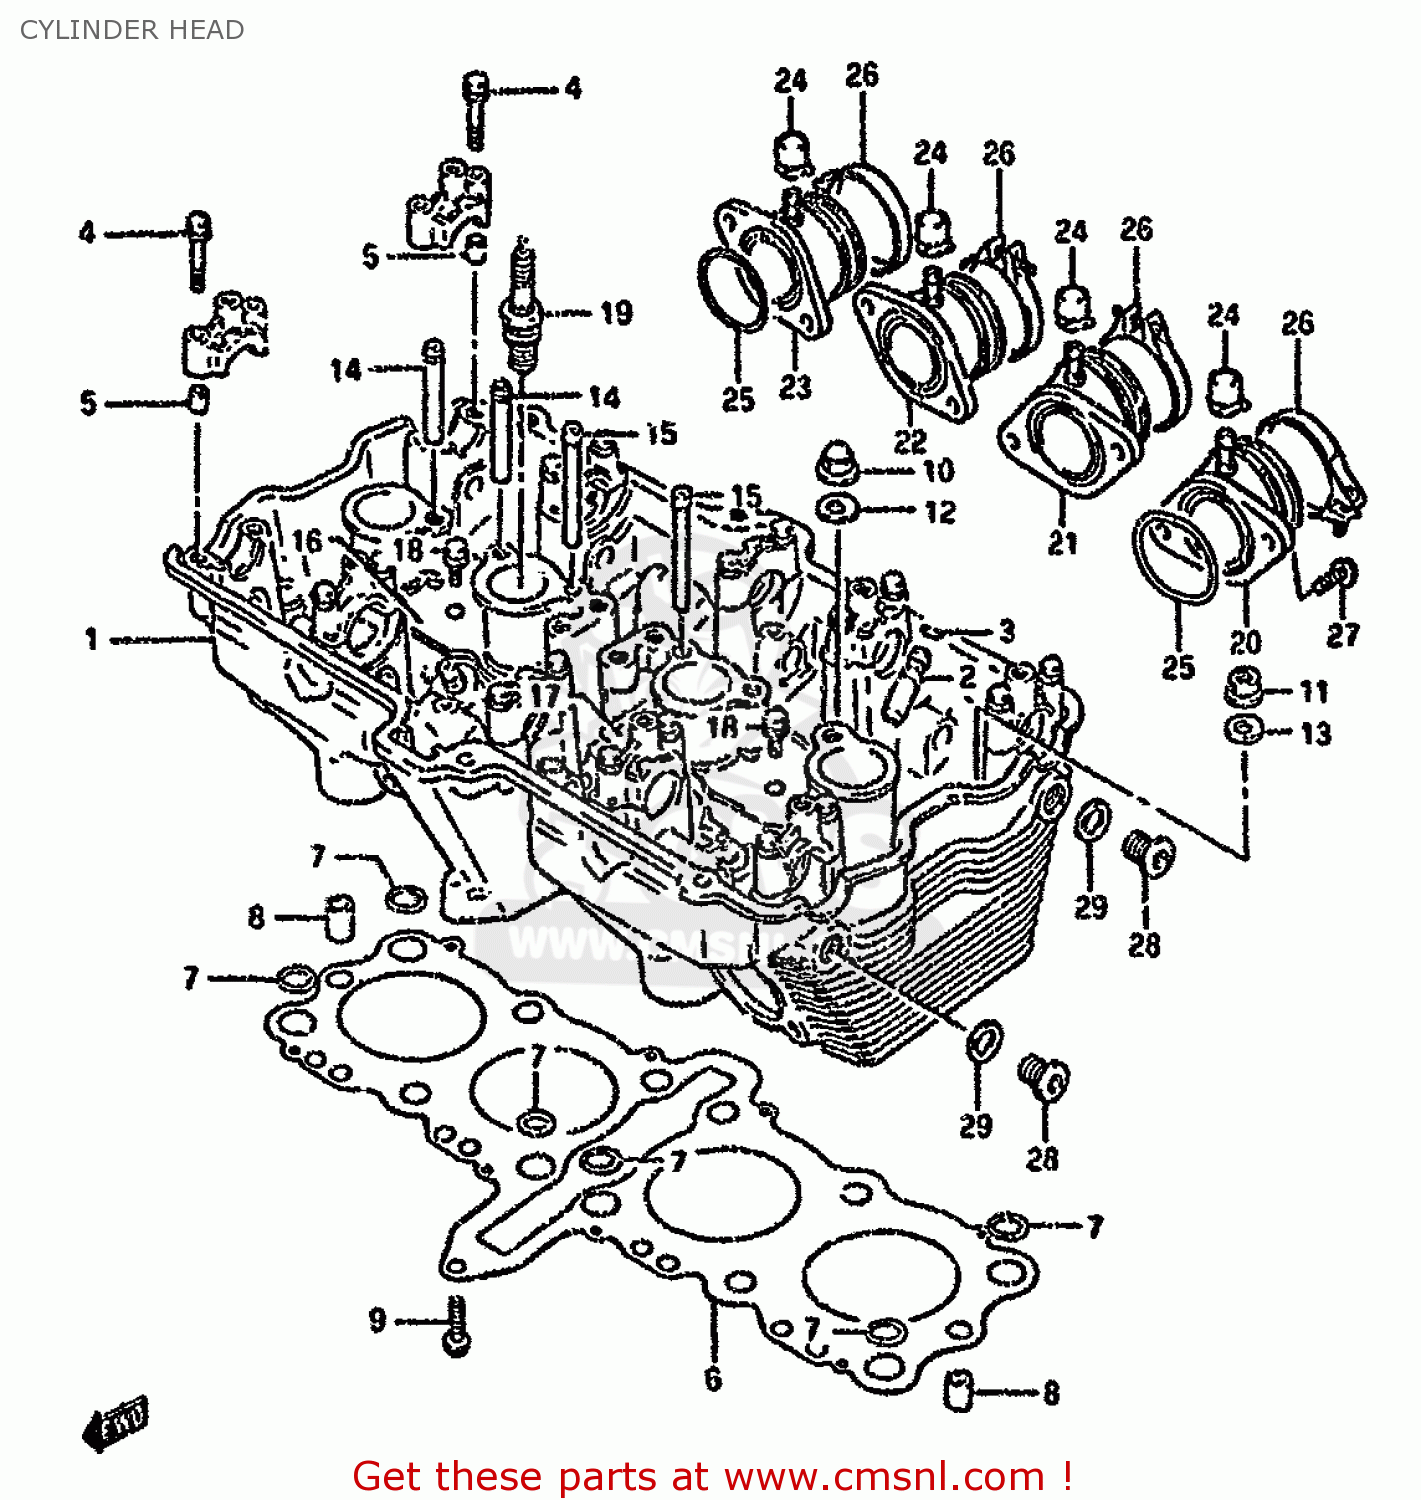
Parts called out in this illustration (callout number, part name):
1	HEAD ASSEMBLY,CYLINDER
2	GUIDE,VALVE
3	RING,SNAP
4	BOLT(6X39)
5	PIN(6.2X8X11)
6	GASKET,CYLINDER HEAD (NAS)
7	O RING(D:2.6,ID:12.1)
8	PIN
9	BOLT
10	NUT
11	NUT
12	GASKET(10.2X20X2).3 (NAS)
13	WASHER (10.5X22X2.3)
14	PIPE,OIL NO.1
15	PIPE,OIL NO.3
16	PLATE,OIL PIPE,R
17	PLATE,OIL PIPE,L
18	BOLT
19	PLUG,SPARK(DR8ES)
20	PIPE,INTAKE NO.1
21	PIPE,INTAKE NO.2
22	PIPE,INTAKE NO.3
23	PIPE,INTAKE NO.4
24	CAP
25	O RING(D:2.4,ID:39.7)
26	CLAMP
27	SCREW
28	PLUG
29	GASKET(13.8X18.8X4.8) (NAS)
